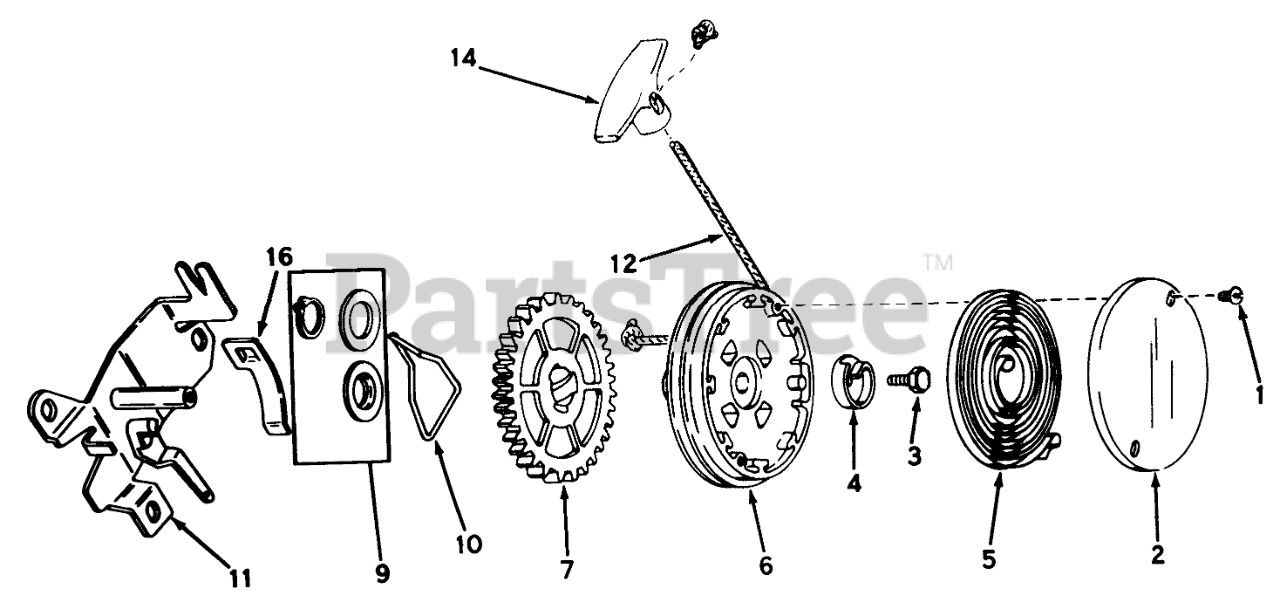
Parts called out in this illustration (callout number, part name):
2	Cover, Spring
3	Screw, Hex Washer Head
4	Hub Spring
5	Spring, Rewind
6	Pulley Assy. (Incl. No. 9)
9	Kit, Thrust Wash. & Snap Rg.
11	Bracket Assy., Mounting
12	Rope-Starter
14	Handle-Starter
16	Clip Rope
